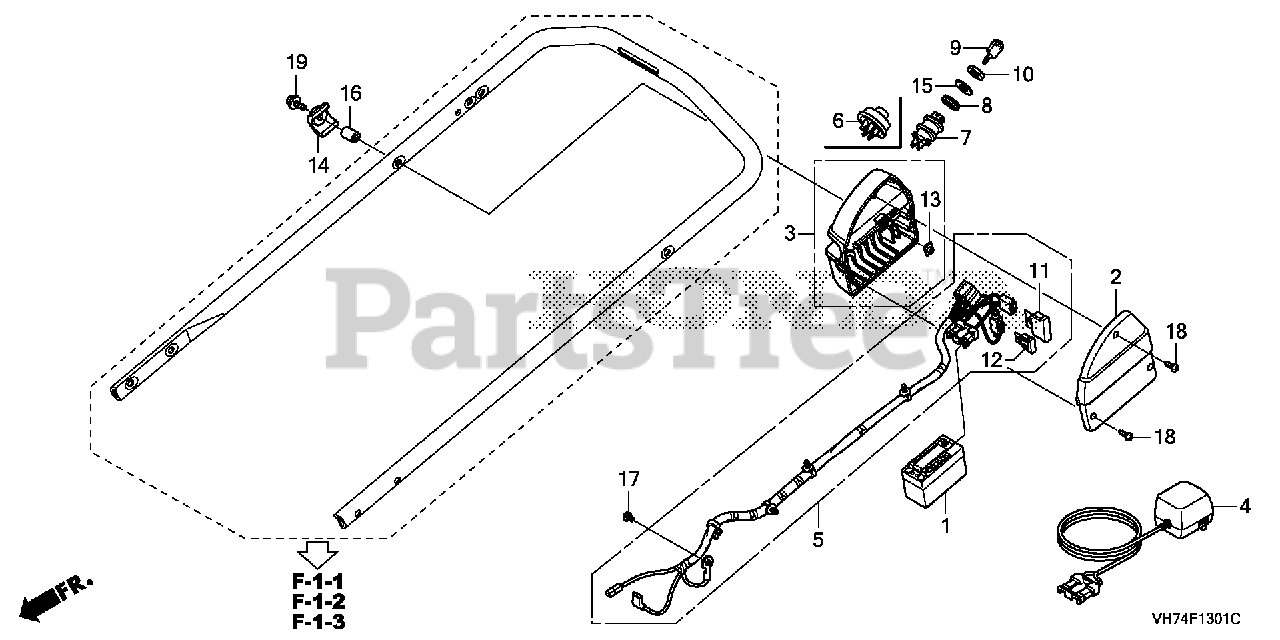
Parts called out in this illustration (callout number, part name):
1	BATTERY KIT (MSDS)
1	BATTERY ASSY. (MSDS)
2	COVER, BATTERY
3	BOX, BATTERY
4	CHARGER ASSY., BATTERY (120V-AC/60HZ)
5	HARNESS ASSY., MAIN
7	SWITCH ASSY., MOMENT
8	BASE, MOMENT SWITCH
10	NUT, SWITCH
12	FUSE, BLADE (3A)
13	NUT, SPECIAL (6X7)
14	WASHER, FRAME JOINT
15	WASHER, SWITCH
16	COLLAR, BATTERY MOUNTING
17	SCREW, PAN (5X8)
18	SCREW, TAPPING (4X16)
19	BOLT, FLANGE (6X35)
